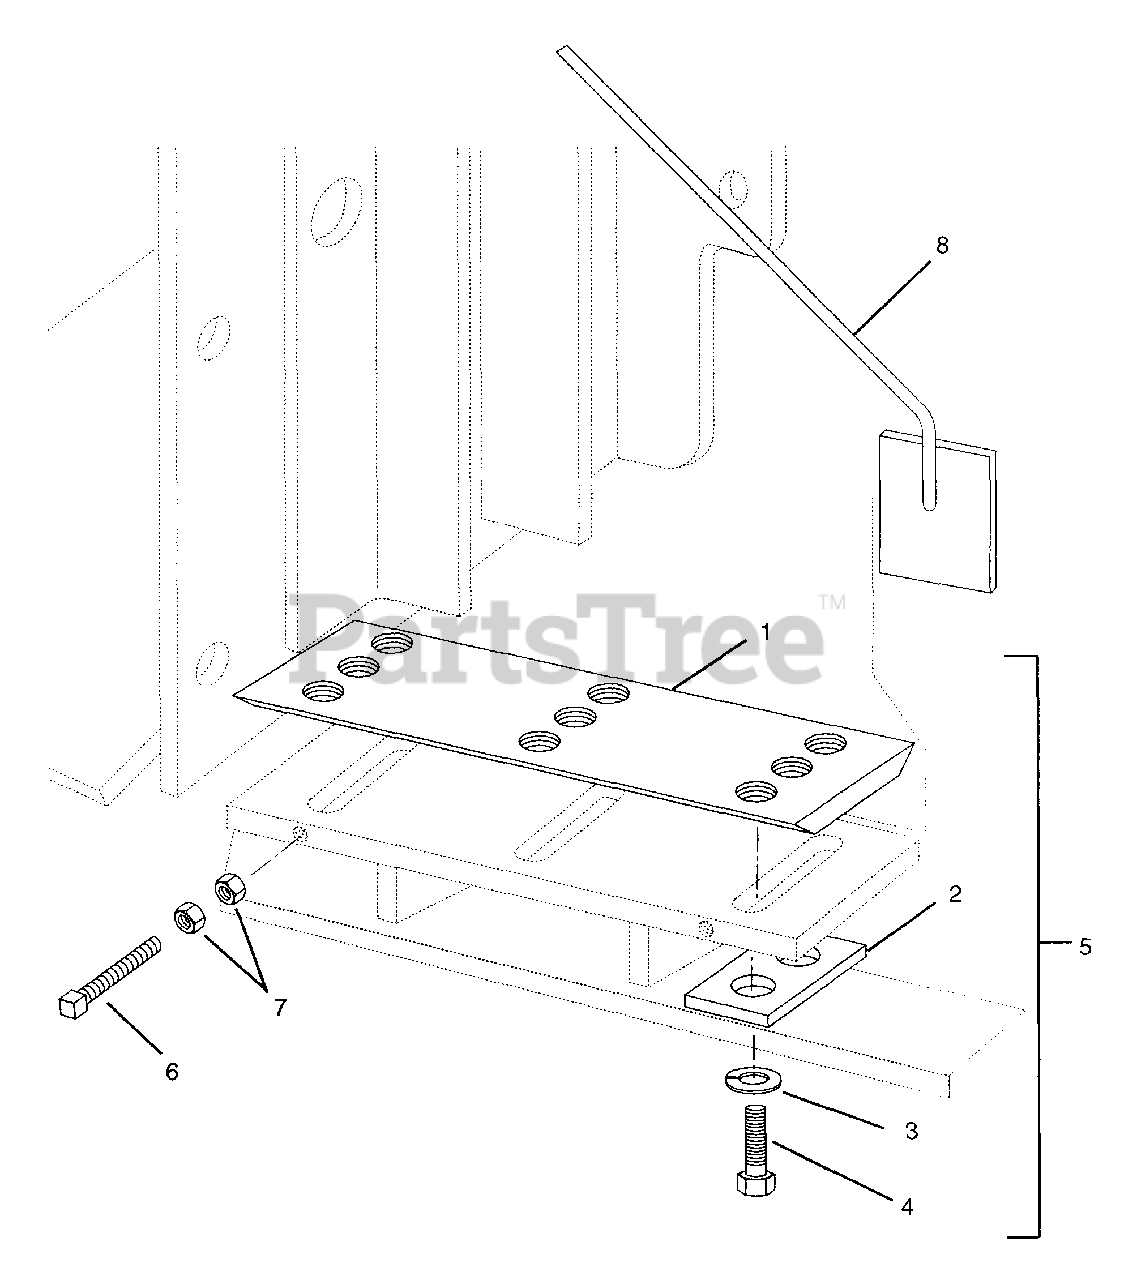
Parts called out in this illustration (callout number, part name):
2	Double Hole Washer
3	Washer-Lock .38 x .115
4	Bolt-Hex .38-24 x 1.25-Grade 8
5	Bed Knife Kit
6	Screw-Set-Square Head .38-16 x 3.50
7	Nut-Hex .38-16-Grade 2
